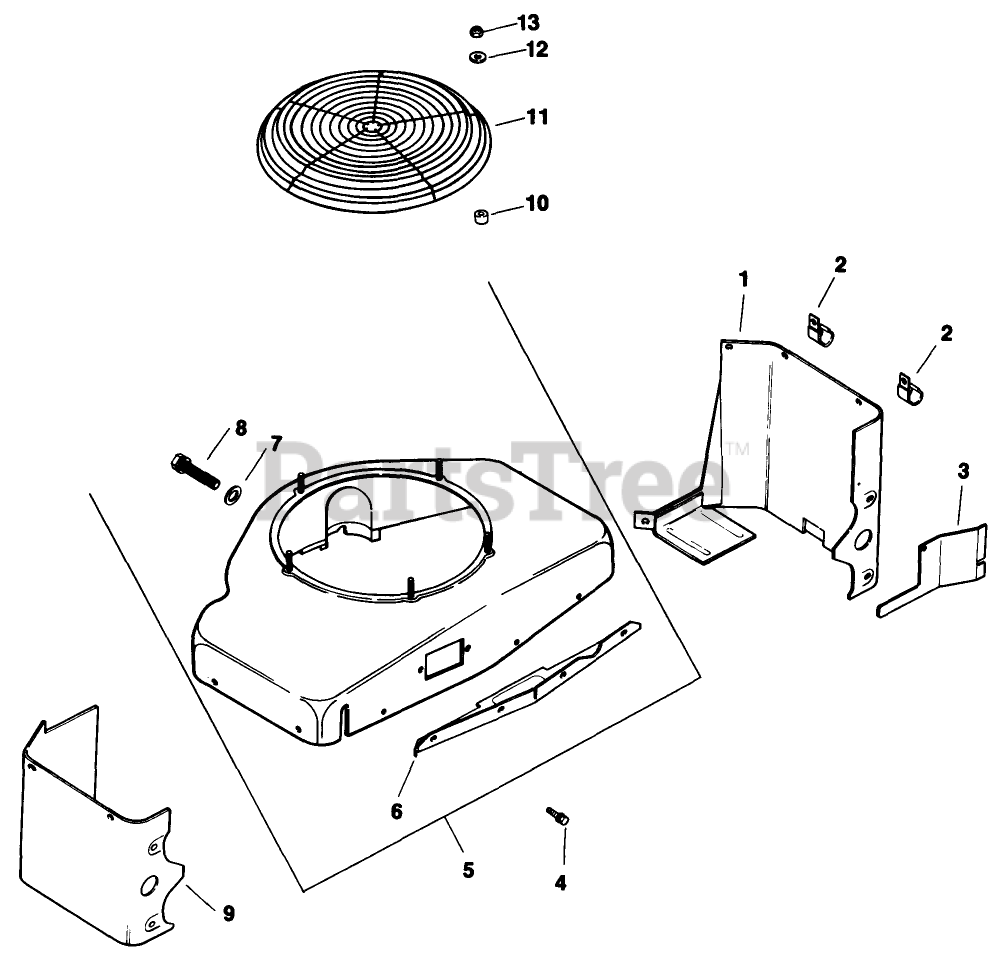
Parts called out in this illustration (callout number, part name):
1	Baffle-Cylinder Head
2	Clip-Cable (Only On: 72103)
3	Baffle-Cylinder Head
4	Screw
5	Kit-Blower Housing
6	Support-Upper Housing
8	Screw-Self Tap
9	Baffle-Cylinder Head
11	GuARd-Grass Screen
13	Locknut
